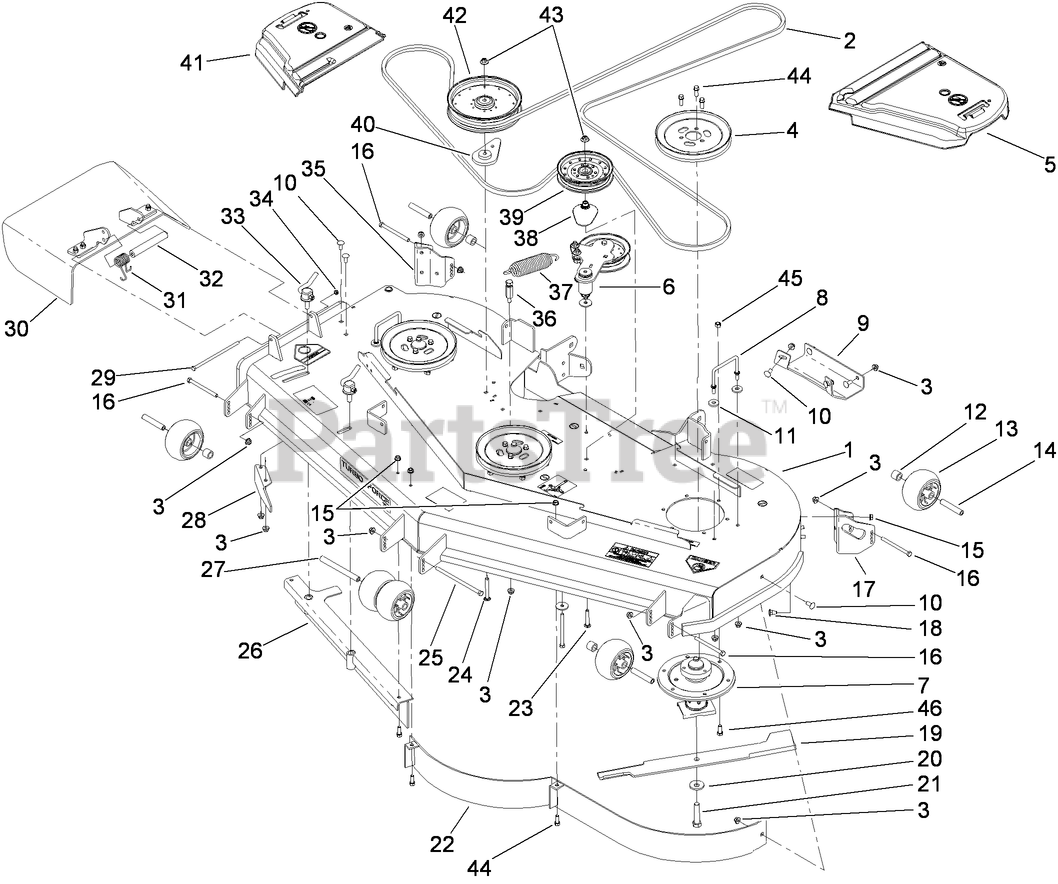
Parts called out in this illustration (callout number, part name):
1	DECK DECAL ASM
2	BELT-V
3	NUT-HF, NI
4	Pulley
5	COVER-BELT, LH
6	ARM-IDLER
7	SPINDLE ASM
8	WIREFORM-COVER
9	PLATE-SKID
10	SCREW-CARR
11	WASHER
12	TUBE-SPACER
13	ROLLER-SCALP, ANTI
14	TUBE-SPANNER
15	NUT-HHF, WHIZ
16	SCREW-HH
17	MOUNT-WHEEL, LH
18	SCREW-CARR
19	BLADE-HI FLOW, 24.5 INCH
20	Washer-Blade Bolt, Heavy
21	Screw-Cap
23	BOLT-CARR, SHORT NECK
24	SCREW-CARR
25	SCREW-HH
27	SPACER-WHEEL
28	BAFFLE-DISCHARGE
29	SCREW-HH
30	RUBBER DEFLECTOR ASM
31	SPRING-TORSION
32	SPACER
33	LEVER ASM
34	NUT-LOCK, NI
35	MOUNT-WHEEL, RH
36	ANCHOR-SPRING, TALL
37	EXTENSION-SPRING
38	SPACER-PULLEY
39	PULLEY-IDLER, FLAT
40	SPACER-IDLER
41	COVER-BELT, RH
42	PULLEY-IDLER
43	NUT-FLANGE, NI
44	SCREW-HWH
45	NUT-LOCK, NI
46	SCREW-HH
